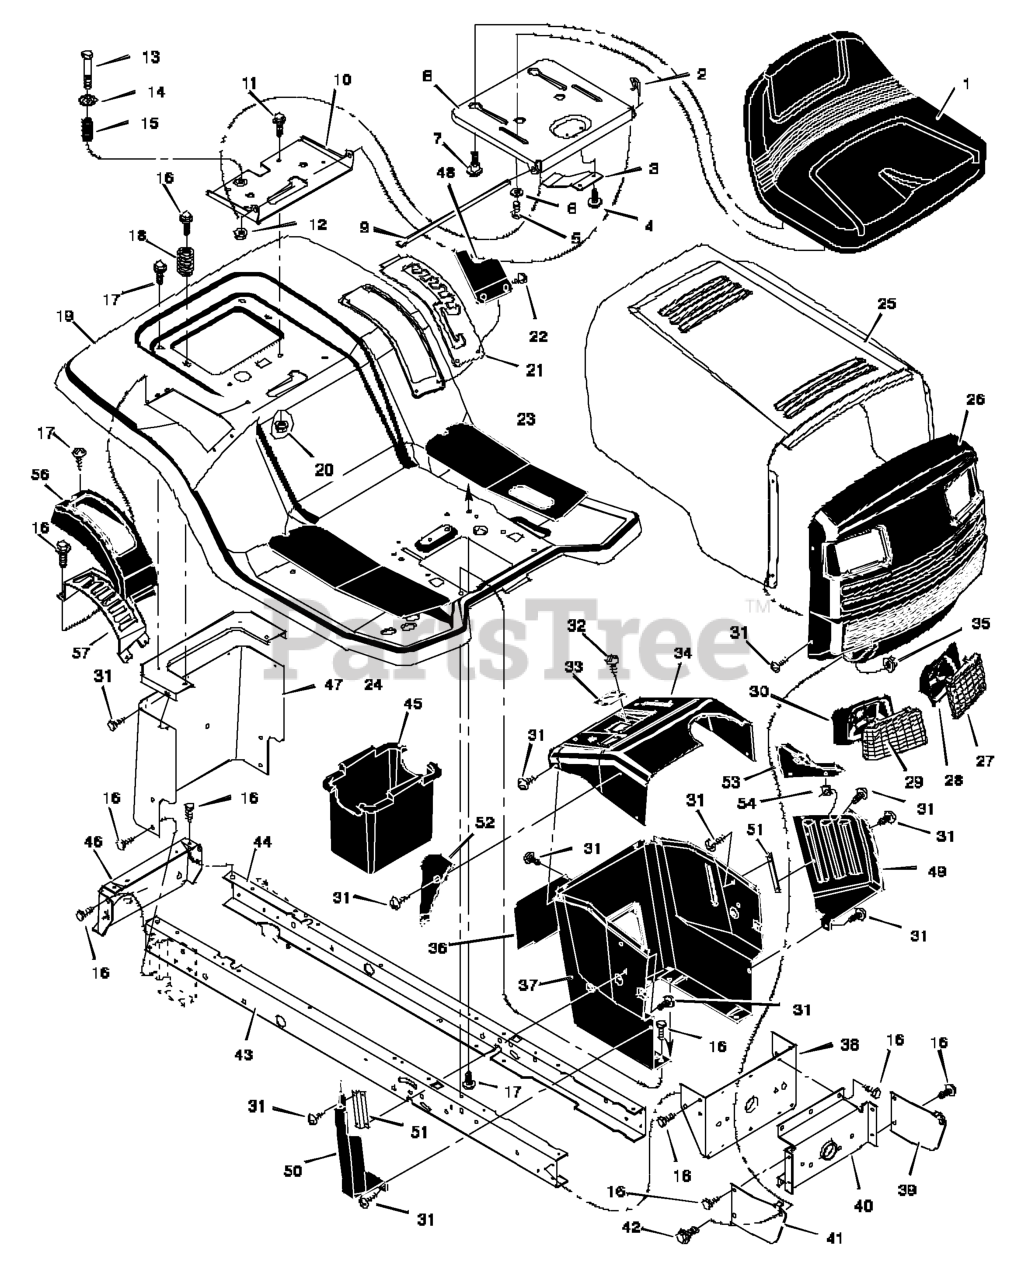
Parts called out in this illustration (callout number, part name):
2	Cap, Push On
5	Bolt, Wing
6	Washer
7	Bolt, Shoulder
8	Support, Seat
9	Rod, Pivot
10	Bracket, Pivot
11	Bolt
13	Bolt, Shoulder
15	Spring
19	Deck, Seat
20	Nut
21	Plate, Index
23	Mat, Left
24	Mat, Right
27	Lens, Left
28	Bezel, Left
29	Lens, Right
30	Bezel, Right
31	Screw
33	Bearing, Steering
35	Nut
36	Panel, Access
37	Support, Dash
38	Bracket, Rear Hanger
39	Support, Left Grille
40	Axle, Hanger
41	Support, Right Grille
42	Bolt, Shoulder
43	Frame, Right
44	Frame, Left
45	Container, Battery
46	Plate, Hitch
47	Panel, Rear
48	Cover, Level Adjustment
49	Panel, Left Side
50	Panel, Right Side
51	Bracket, Panel
52	Cap, Panel
53	Cap, Left Panel
54	Retainer
55	Plate, Rear
56	Cover, Shift Gate
57	Shift Gate
